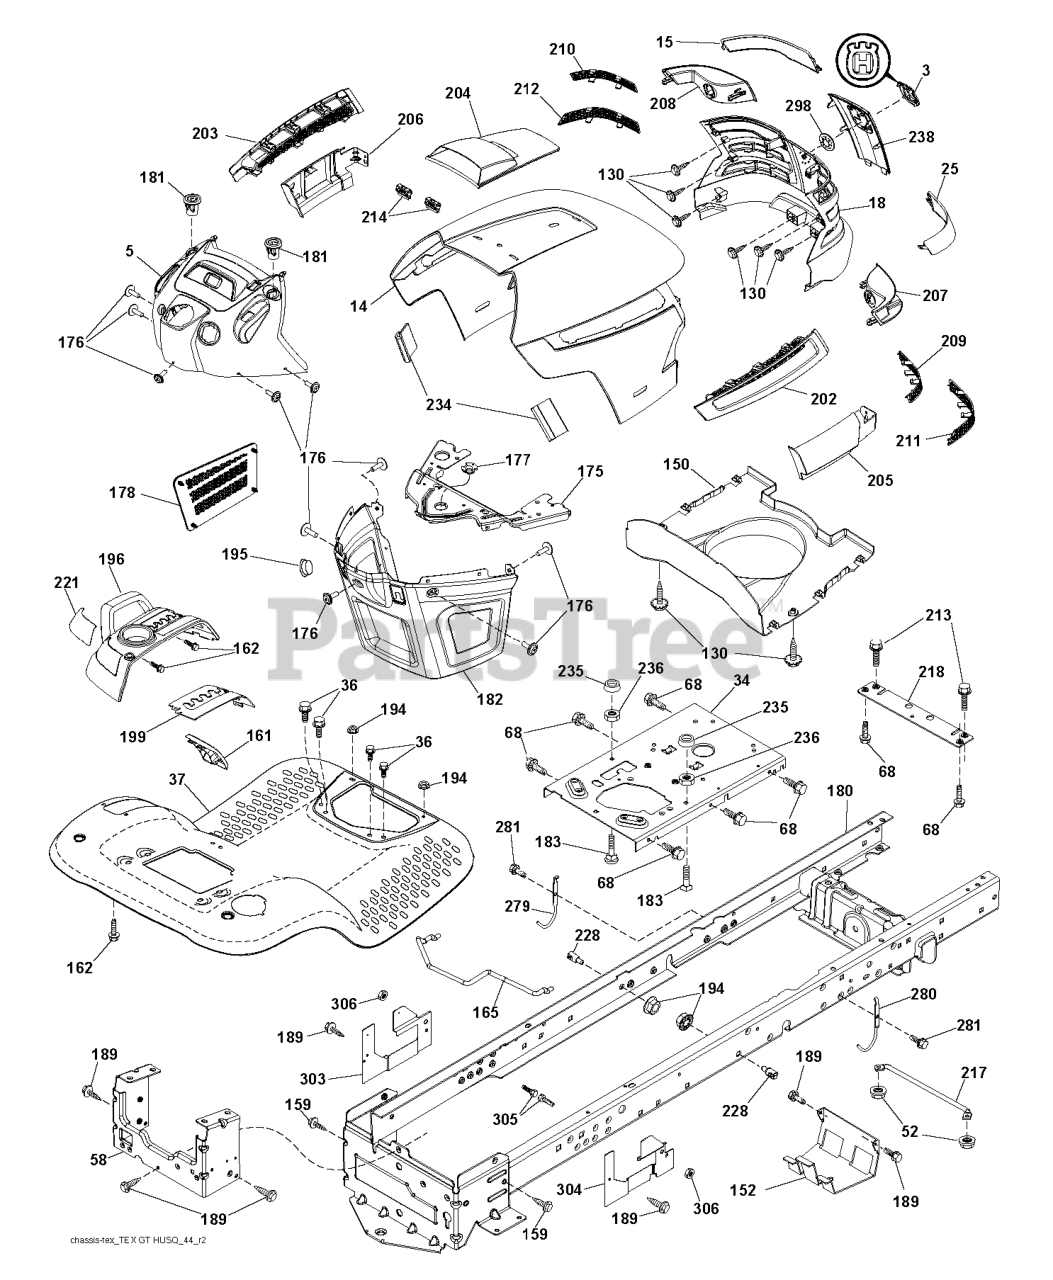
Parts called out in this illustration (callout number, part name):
3	RP LOGO
5	DASH.ASM.HUSQ.GT.E.RECT.W/CK
14	HOOD
15	LENS.LH.TEX.GT.HUSQ.CL
18	GRILL.ASM.HUSQ.TG/CRD.W/TRIM
25	LENS.RH.TEX.GT.HUSQ.CL
34	PLATE.ENGINE.WELDED.CHASSIS
36	SCREW 5/16"
37	FENDER.PNT.TX.GT.CH/FW.ORANGE
52	LOCKNUT
58	DRAWBAR.UPPER.2PC,LRG.FENDER
68	Screw 5/16-18 x 1/2 Hex, Self Tapping 5/16-18 x 1/2
130	SCREW.#10 X 0.750.BOS
137	BUMPER DASH
150	AIR.DUCT.HOOD.TEX.GT.HUSQ
152	SHIELD.BROWNING.W/TEX
159	SCREW, 3/8-16X3/4
161	CONSOLE.FUEL.WINDOW.HU
162	SCREW.HI-LO.CONSOLE
165	SUPPORT.TANK.REAR.W/TEX
175	PLATE.CROSSMEMBER.HUSQ
176	SCREW.#10-24X5/8.RN.QU
177	BUSHING, STEERING
178	CARGO.ASM.NET.TXGT.W/C
180	CHASS.WLDMNT.TL.12GA/2P.48/54
181	BUSHING.MNT.FEND.CRGO.
182	DASH.LOWER.COMMON.12V.ADAPTOR
183	BOLT.5/16-18X1-1/4 FULL.THREAD
189	SCREW
194	NUT LOCK HEX FLANGE 5/16-18
196	RP CONSOLE.ASM.DECKLFT.W/
199	PLATE.DECK.LIFT.HUSQVARNA.GT
202	VENT.SIDE.HOOD.HUSQ.RH.GREY
203	VENT.SIDE.HOOD.HUSQ.LH.GRAY
204	HOOD VENT
205	SKIRT.HOOD.SIDE.HUSQ.RH.GREY
206	SKIRT.HOOD.SIDE.HUSQ.LH.GREY
207	BEZEL.RH.TEX.GT.HUSQ
208	BEZEL.LH.TEX.GT.HUSQ
209	INSERT.HEX.GRILL.HUSQ.GREY
210	INSERT.HEX.GRILL.HUSQ.
211	INSERT.HEX.GRILL.HUSQ.
212	INSERT.HEX.GRILL.HUSQ.
213	BOLT
214	CLIP.RETAINER.TINNER.
217	ROD.PIVOT.HOOD
218	X-PIECE.HOOD.STOP.NON/
221	REFLECTOR.LH.TEX GT HU
228	STUD.FASTNER.W/ANTI-ROTATE
234	BUMPER.HOOD.TEX.HUSQVARNA
235	SPACER FENDER
236	NUT.CENTERLOCK.5/16-
238	TRIM.HUSQ.TG/CRD.SERVICE
279	ROD UPSTOP
280	ROD UPSTOP
281	SCREW 3/8-16X1
298	NUT PUSH M
303	SHIELD CHASSIS LEFT
304	SHIELD CHASSIS RIGHT
306	NUT LOCK FLG 3/8-16 UNC
